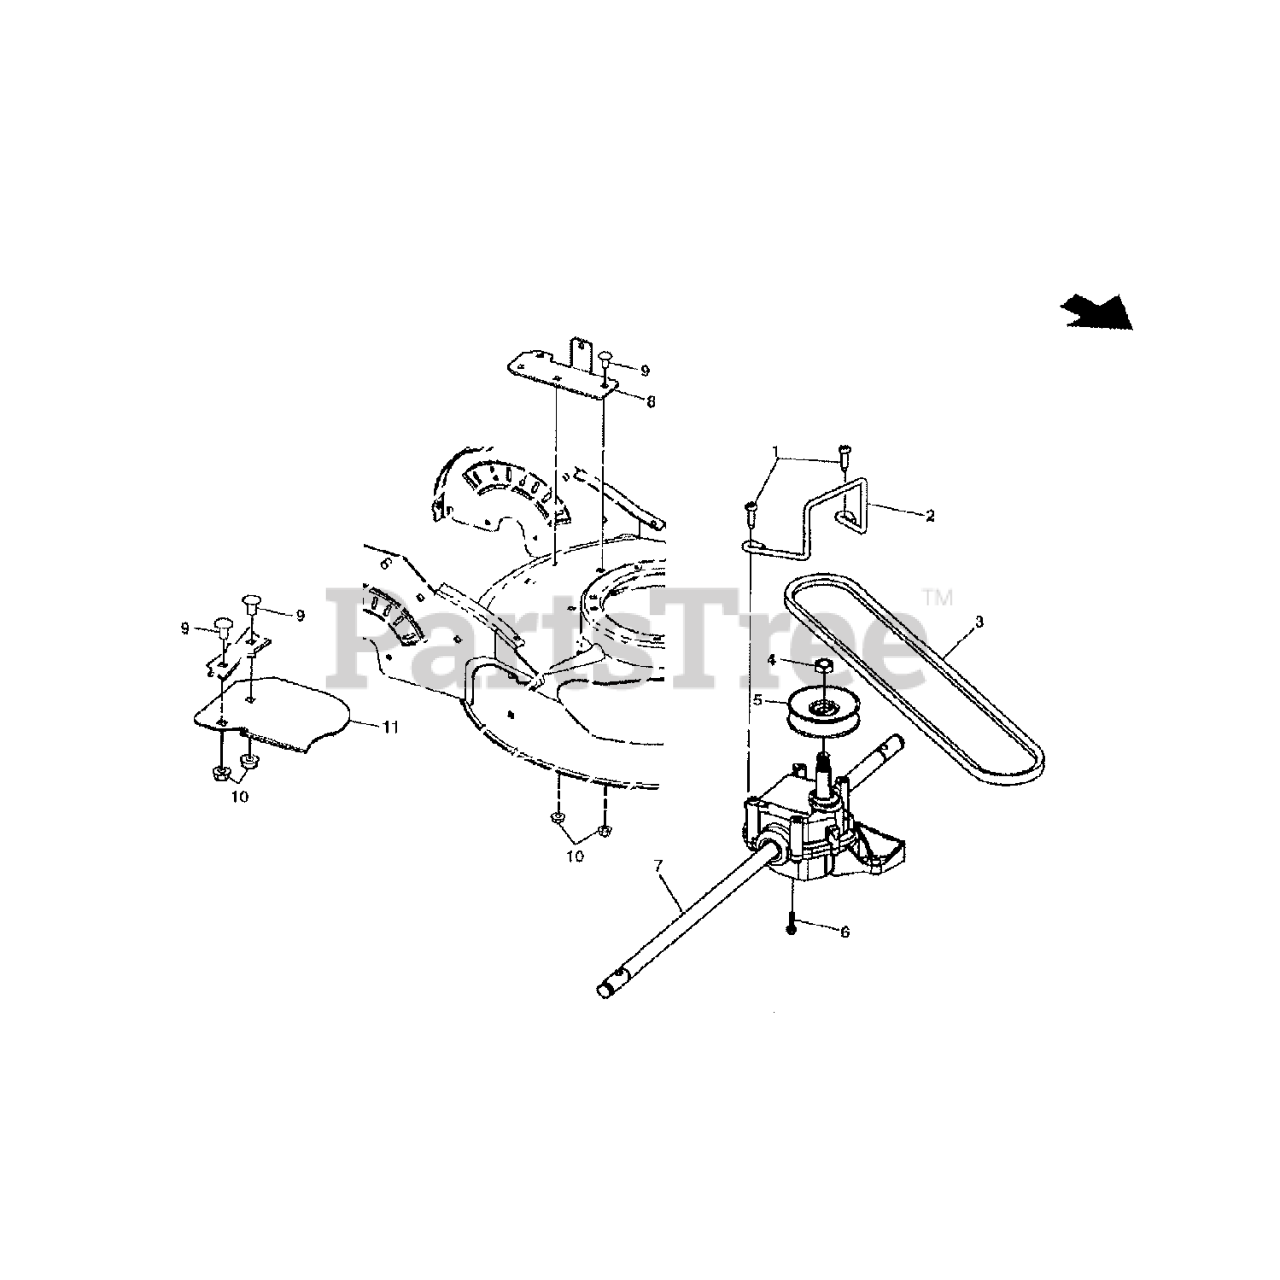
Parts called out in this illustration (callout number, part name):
1	PHST, #10-16 X 3/4, COMBO
2	BELT GUIDE, TRANSMISSION
3	BELT, 3L, TRACTION DRIVE, 21" PIVOT HANDLE
4	HCLN, JAM, 3/8-16 YZ
5	PULLEY, TRANS VAR SPD LC WBM
6	SCREW, 7MM X 1 X .550, AB POINT
7	TRANSMISSION, ROCKER, 21" WBM
8	BRACKET, TRANSMISSION MOUNTING
9	RHSSNB, 5/16CX5/8
10	FLN, 5/16-18 YZ
11	SHIELD, DEBRIS
